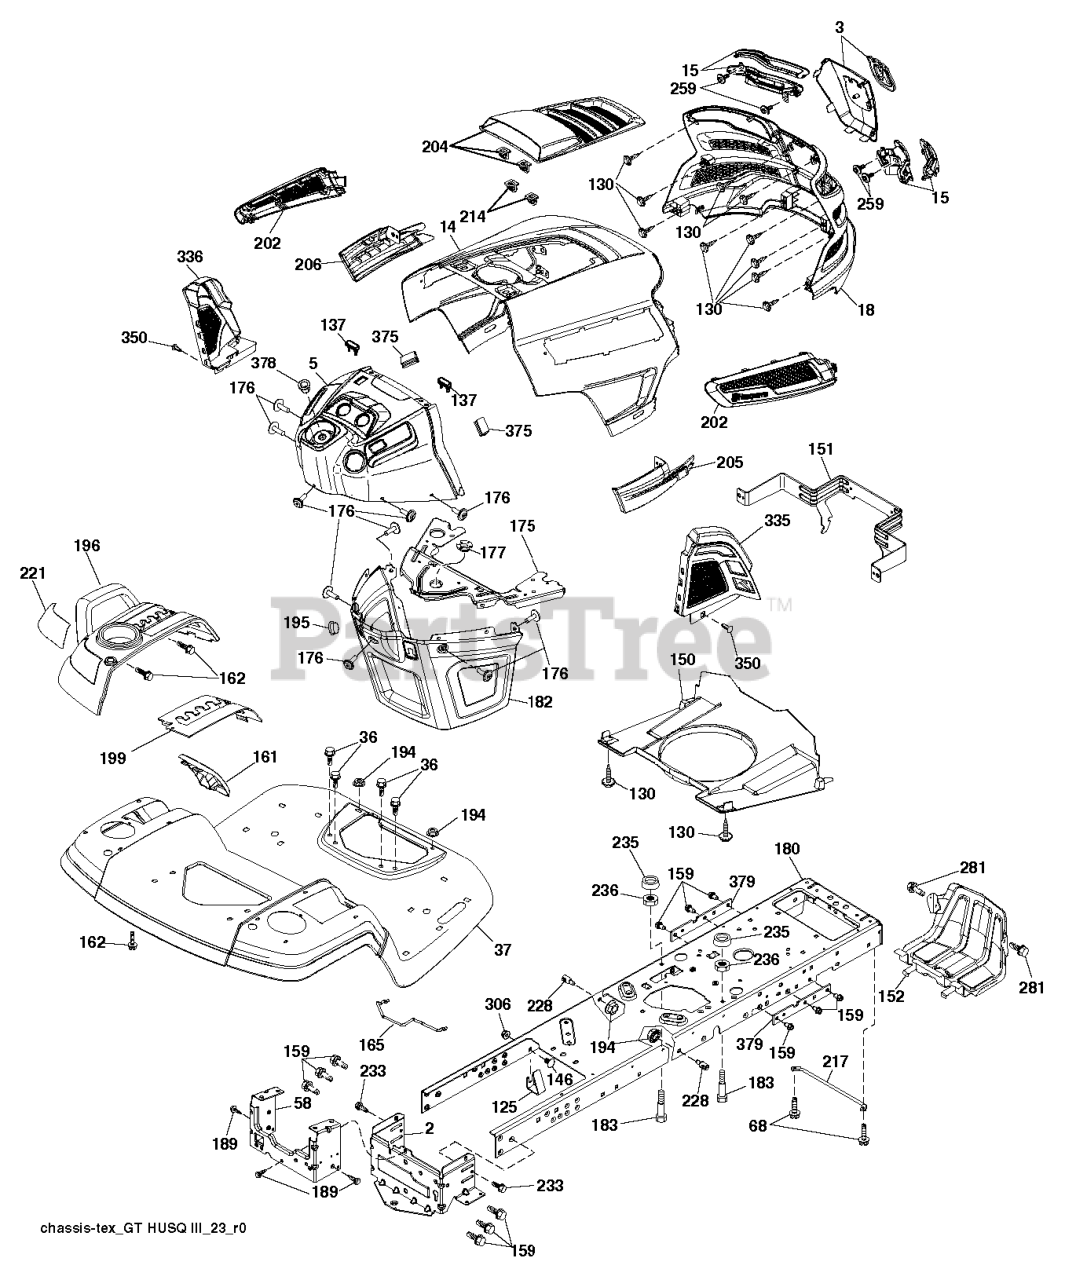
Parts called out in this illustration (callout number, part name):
2	DRAWBAR.LOWER.2PC.18/22
3	Covers
5	DASH.UPR.GT2.DUAL.RD.PT
14	HOOD.ASM.HUSQVARNA.GT.TEX.ORAN
15	Service Kit
36	SCREW 5/16"
37	FENDER.PNT.TX.GT.CH/FW/DL.HUSQ
58	DRAWBAR.UPPER.2PC,LRG.FENDER
125	CLIP.FUEL.LINE
137	BUMPER DASH
146	BOLT.RDHD.SHT.SQNK.3/8-16X5/8
150	AIR.DUCT.GTV.BLACK
151	BRACKET.PIVOT.HOOD.GT.HUSQ.II
152	SHIELD.BROWNING.PNT.GT.V2
159	SCREW, 3/8-16X3/4
161	CONSOLE.WINDOW.FUEL.HUSQ.GT
165	SUPPORT.TANK.REAR.B/TE
175	PLATE.PNT.CROSSMEMBER.HUSQ/PRE
176	SCREW.#10-24X5/8.RN.QU
177	BUSHING STEERING
180	CHASSIS.LT/GT.BOLTED
182	DASH.LOWER.COMMON.12V.ADAPTOR
189	SCREW
195	PLUG.HOLE.DASH.LOWER.12V.BLK
196	SUBASM.CONSOLE.HUSQ.GT.DECKLFT
199	PLATE.DECK.LIFT.HUSQVARNA.GT
202	Vents
204	Vents
205	SIDE.TRIM.RH.GT.HUSQ.II
206	SIDE.TRIM.LH.GT.HUSQ.II.GRAY
214	CLIP.RETAINER.TINNER.
217	ROD.PIVOT.HOOD
221	REFLECTOR.LH.TEX GT HU
228	STUD.W/"D"ANTI-ROTATION
233	BOLT.SHOULDER
236	NUT.CENTERLOCK.5/16-
281	SCREW 3/8-16X1
306	NUT LOCK FLG 3/8-16 UNC
335	COVER.LOWER.DASH.RH.BLACK
336	COVER-LH.LOWER.DASH.GT2.BLACK
350	CLIP.X-MAS.TREE
375	BUMPER CLIP-ON. DASH 1"
378	BUSHING FLANGE; PLASTIC
379	CHASSIS.PLATE.REINFORCEMNT.431
